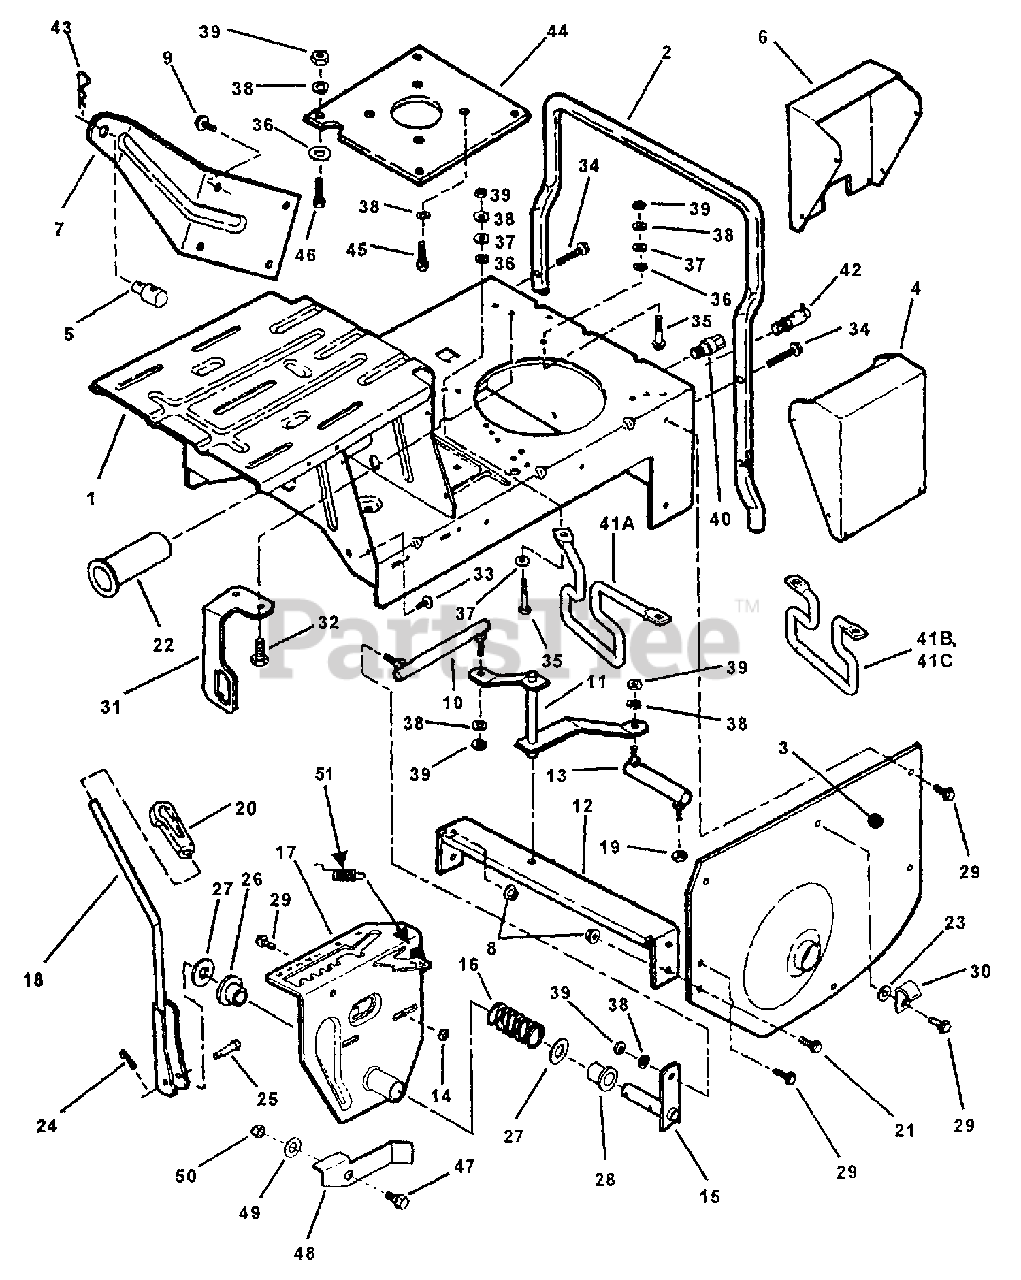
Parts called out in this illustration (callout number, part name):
1	CASE, Main (Standard)
1	CASE, Main (Commercial)
2	BUMPER, Rear
3	FENDER, Left Hand
4	COVER, Battery
5	SWIVEL
6	COVER, Switch
7	WING, Rear
8	NUT, 5/16-18 Hex Flange Lock, Grade 5
9	SCREW, 5/16-18 x 3/4" Hex Washer Self-Tap
10	LINK, Shift (Long)
11	ARM, Shift
12	CROSS BRACE
13	LINK, Shift (Short)
14	NUT, 5/16-18 Hex
15	ARM, Shift Handle
16	SPRING, Shift Handle
17	ASSEMBLY, Shift Detent
18	HANDLE, Shift
19	NUT, 5/16-24 Hex Flange Lock
20	KNOB, Shift Handle
21	SCREW, 5/16-18 x 3/4" Hex Head Cap, Grade 2
22	BUSHING, Pilot
23	WASHER, 5/16" Internal Tooth Lock
24	COTTER-PIN, 3/32 x 3/4"
25	PIN, 1/4 x 1-3/4" Tapered Clevis
26	BUSHING, Nylon
27	WASHER, Thrust
28	BUSHING, Nylon
29	SCREW, 5/16-18 x 5/8" Hex Washer Self-Tap )
30	CLIP, Wire
31	BRACKET, Switch
32	SCREW, #10-32 x 1/4" Hex Washer Self-Tap (slotted)
33	FASTENER, 1/4 x 3/4" Ratchet
34	SCREW, 5/16-18 x 1-1/2" Hex Washer Self-Tap
35	SCREW, 5/16-24 x 1-3/4" Hex Head Cap, Grade 5
36	RETAINER, 5/16" Bolt
37	WASHER, 5/16" Flat
38	WASHER, 5/16" Split Lock
39	NUT, 5/16-24 Hex, Grade 5
40	DRAIN, Oil (Short)
41A	GUIDE, Belt (9.48" Bolt Pattern Bent Top)
41B	GUIDE, Belt (5.74" Bolt Pattern, 5.625" Belt Gap)
41C	GUIDE, Belt (5.74" Bolt Pattern, 5.0" Belt Gap)
42	ASSEMBLY, Oil Valve
43	HAIRPIN, 3/32 x 1-1/2"
44	PLATE, Engine
45	BOLT, M8-1.25 x 25mm Hex Head Self-Tap
46	SCREW, 5/16-24 x 1" Hex Head Cap, Grade 5
47	BOLT, 5/16-18 Shoulder
48	LEVER, Over-Ride
49	WASHER, 7/16" Flat
50	NUT, 5/16-18 Nyloc
51	SPRING
